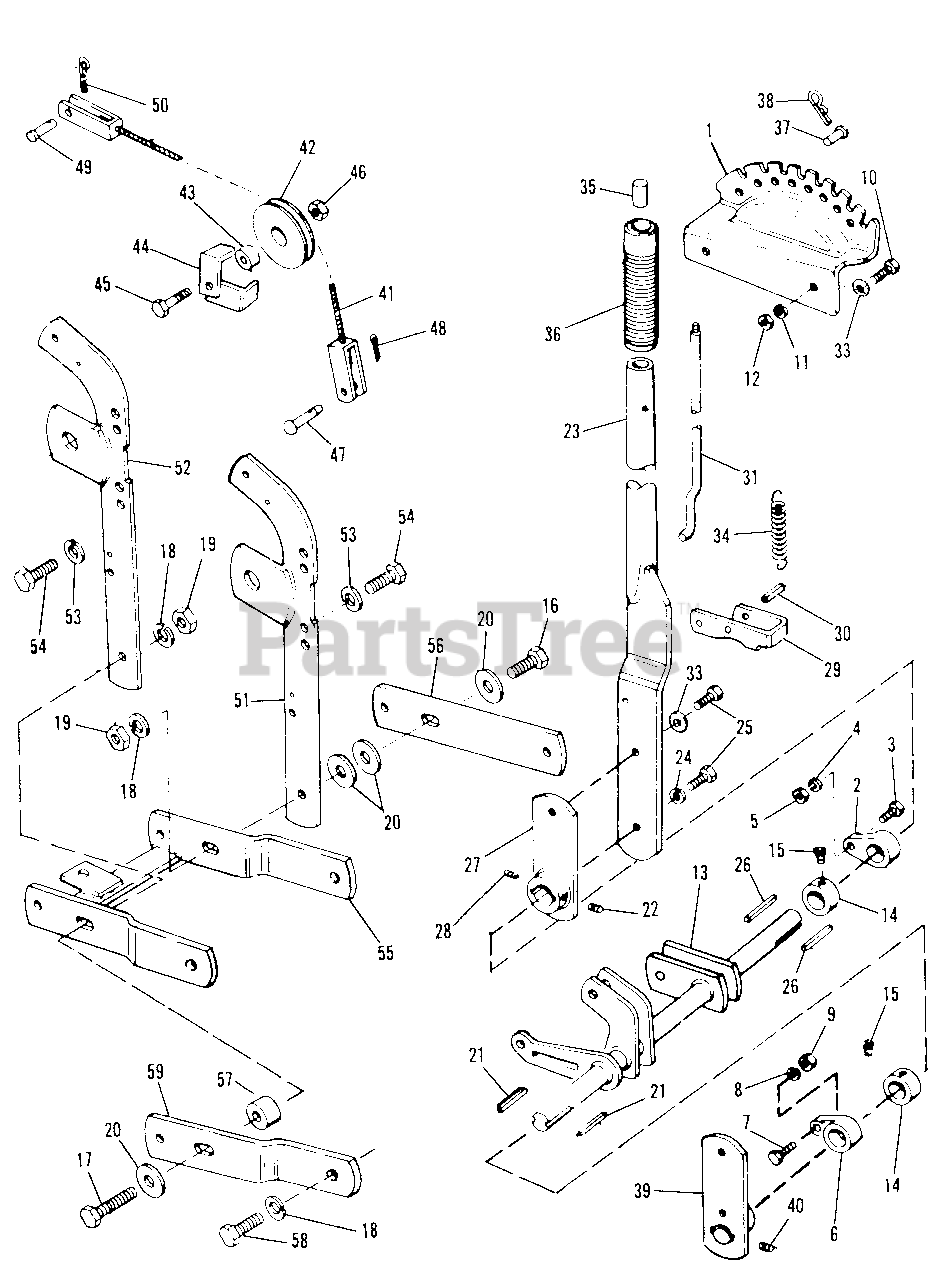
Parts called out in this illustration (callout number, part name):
1	QUADRANT, Lift Lever
2	BEARING, Lift Lever
3	CAPSCREW, Hex, 5/16"-18 x 1-1/4" lg.
4	LOCK WASHER, 5/16"
5	NUT, Hex, Full, 5/16"-18
6	BEARING, Lift Lever
7	CAPSCREW, Hex, 5/16-18 x 1-1/4" lg.
8	LOCKWASHER, 5/16"
9	NUT, Hex, Full, 5/16"-18
10	CAPSCREW, Hex, 3/8"-16 x 3/4" lg.
11	LOCKWASHER, 3/8"
12	NUT, Hex, Full, 3/8"-16
13	SHAFT ASSEMBLY, Lift
14	COLLAR, Set
15	SCREW, Set, 5/16"-18 x 3/8" lg.
16	CAPSCREW, Hex, 7/16"-14 x 1-1/2" lg.
17	CAPSCREW, Hex, 7/16"-14 x 1-3/4" lg.
18	LOCKWASHER, 7/16"
19	NUT, Hex, Full, 7/16"-14
20	WASHER, Plain, 5/16"
22	SCREW, Set, 5/16"-18 x 1/4" lg.
23	LEVER ASSEMBLY, Lift
24	LOCKWASHER, 3/8"
25	CAPSCREW, Hex, 3/8"-16 x 1" lg.
27	LEVER ASSEMBLY, Lift
28	SCREW, Set, 5/16"-18 x 1/4" lg.
29	LATCH, Lift Lever
30	PIN, Roll, 3/8" x 1-1/4" lg.
31	ROD, Latch
33	WASHER, Plain, 3/8"
35	BUTTON, Thumb
36	GRIP, Handle
38	CLIP, Spring
39	LEVER ASSEMBLY, Front Lift
40	SCREW, Set, 5/16"-18 x 1/4" lg.
41	CABLE ASSEMBLY, Lift
44	GUARD, Cable
46	NUT, Hex, Jam, Lock, 3/8-16
47	PIN
48	PIN, Cotter, 3/32" x 7/8" lg.
50	CLIP, Spring
51	ARM ASSEMBLY
52	ARM ASSEMBLY
53	LOCKWASHER, 7/16"
54	CAPSCREW, 7/16"-14 x 1" lg.
55	DRAW BAR ASSEMBLY
56	BAR, Pull
58	CAPSCREW, 7/16"-14 x 2-1/4" lg.
59	BAR, Draw
